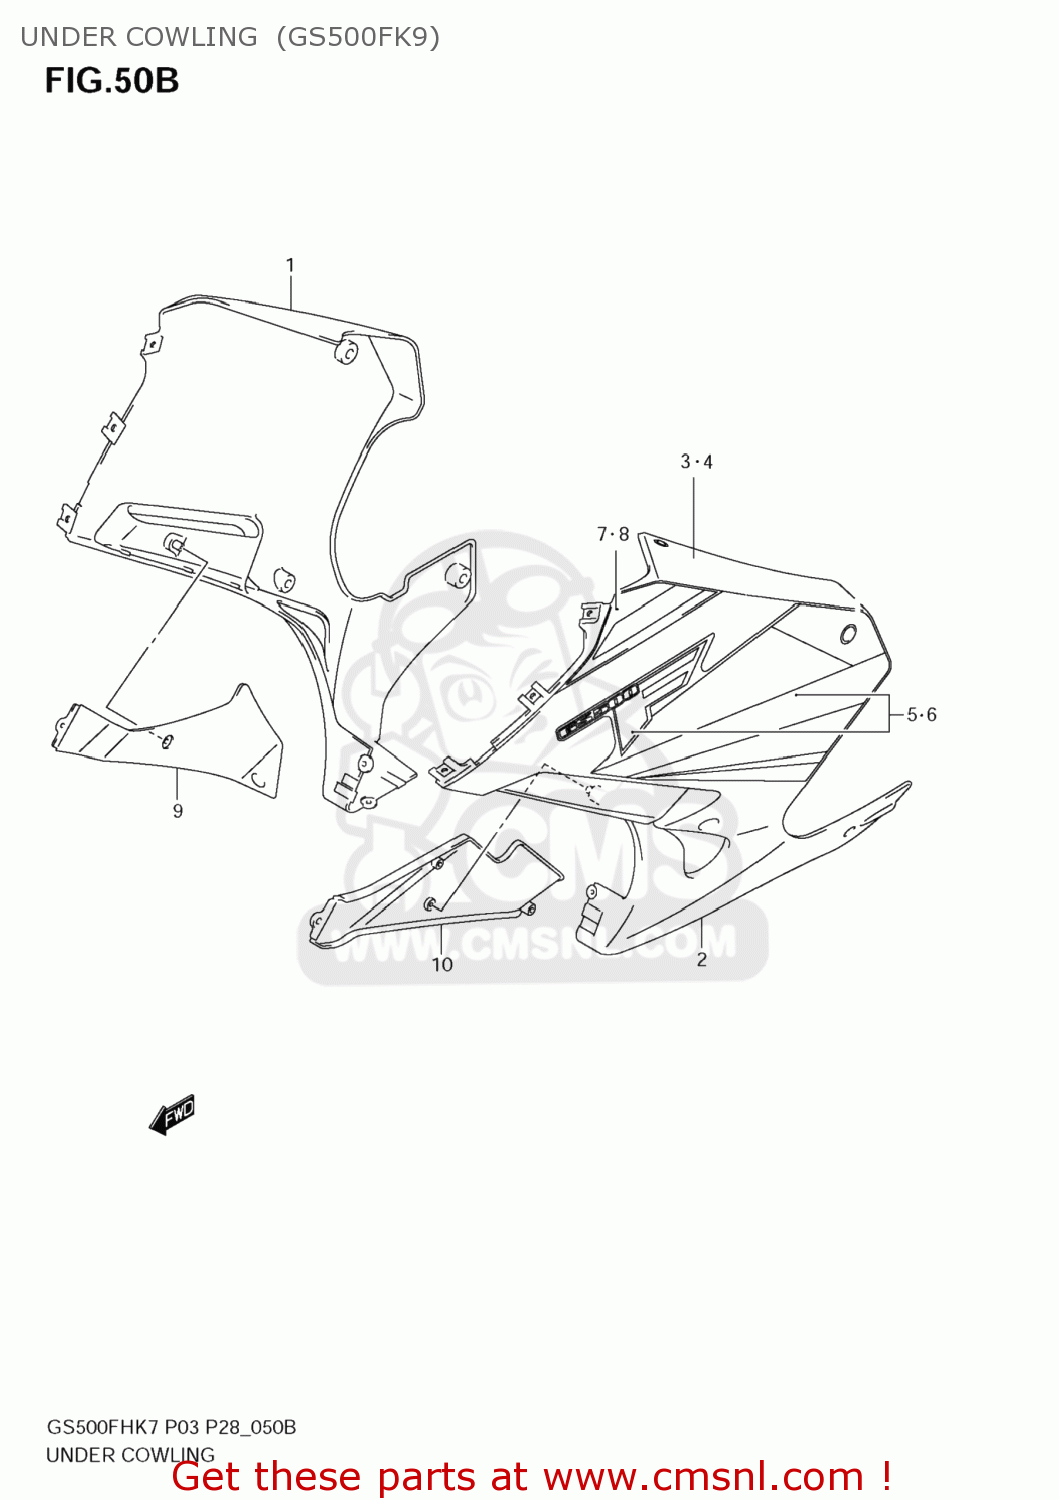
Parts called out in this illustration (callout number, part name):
1	COWL, UNDER RH (WHITE)
2	COWL, UNDER LH (WHITE)
3	TAPE GS500
4	TAPE,UPPER
5	TAPE,COWL UNDR
6	TAPE,COWL UNDR
7	TAPE,COWL UNDR
8	TAPE,COWL UNDR
9	COWLING, INNER
10	COWLING, INNER
11	SHIELD,UNDER C
12	SHIELD,UNDER C
13	SHIELD,UN. HEA
14	SHIELD,UN.HEAT
